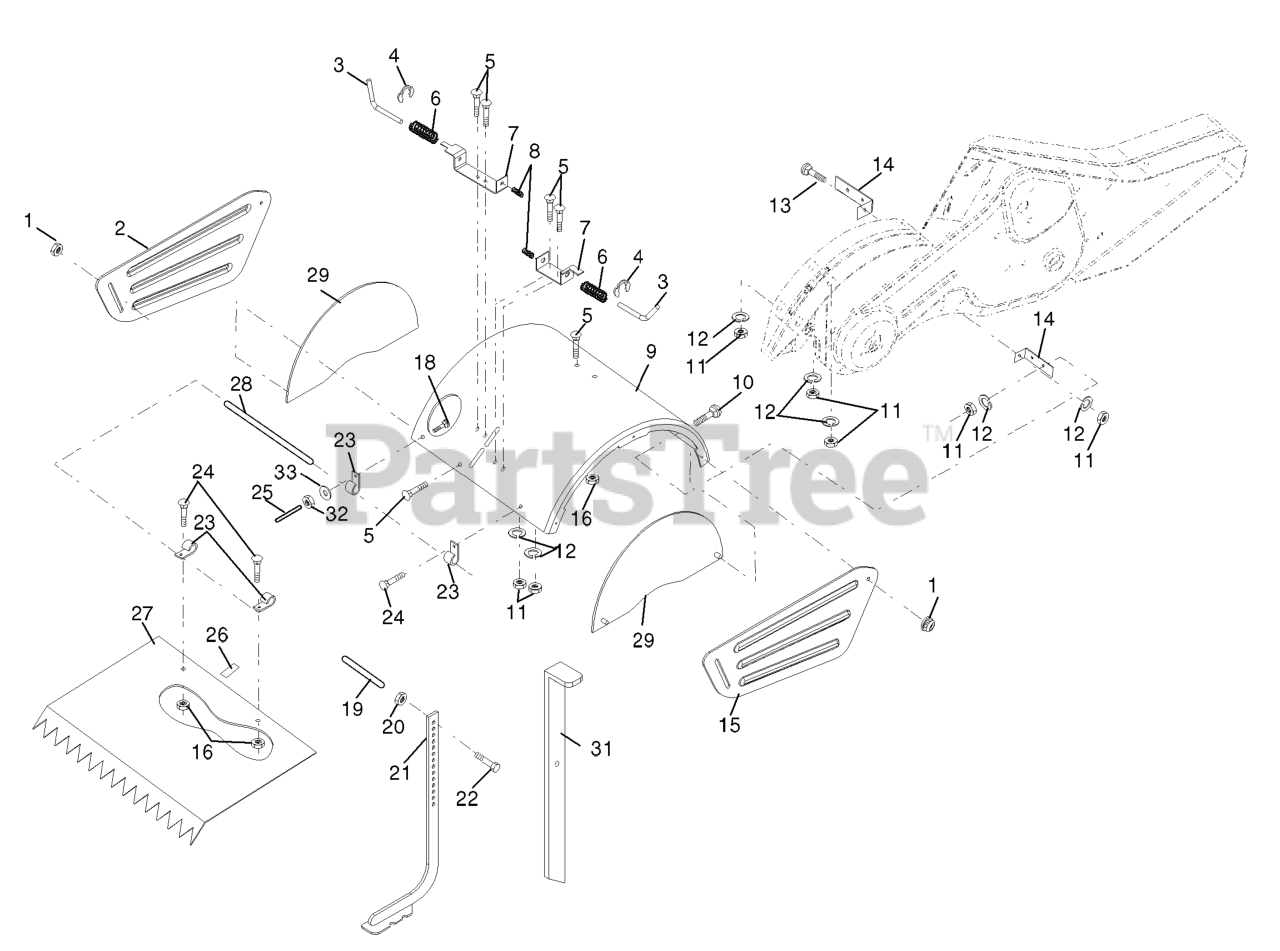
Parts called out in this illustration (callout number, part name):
1	NUT LOCK HEX FLANGE 5/16-18
2	SHIELD
3	STAKE PIN TI
4	RING, KLIP
5	BOLT, RDHD SQNK 5/16-18 X 3/4
7	BRACKET.LATCH.STAKE.3.20.BLACK
8	SPRING CRT
9	SHIELD.PNT.TINE.17"M
10	BOLT
11	NUT
12	WASHER.LOCK.HVY.HLCL.SPR.5/16
13	BOLT.CARRIAGE.5/16-18
14	BRACKET.TINE.SHIELD.TILLER
15	SIDE SHIELD RH
16	NUT T
20	NUT.HEX.3/8-16UNC
21	STAKE.DEPTH.16.CRT.BLACK
22	BOLT.375-16
24	BOLT
26	PAD IDLER TI
27	SHIELD LEVELING
28	PIN.HINGE.TILLER
29	SHIELD.ASM.SIDE.ORANGE.(OLD)
31	STAKE.PNT.DEPTH.DRAG
32	NUT
33	LOCKWASHER
